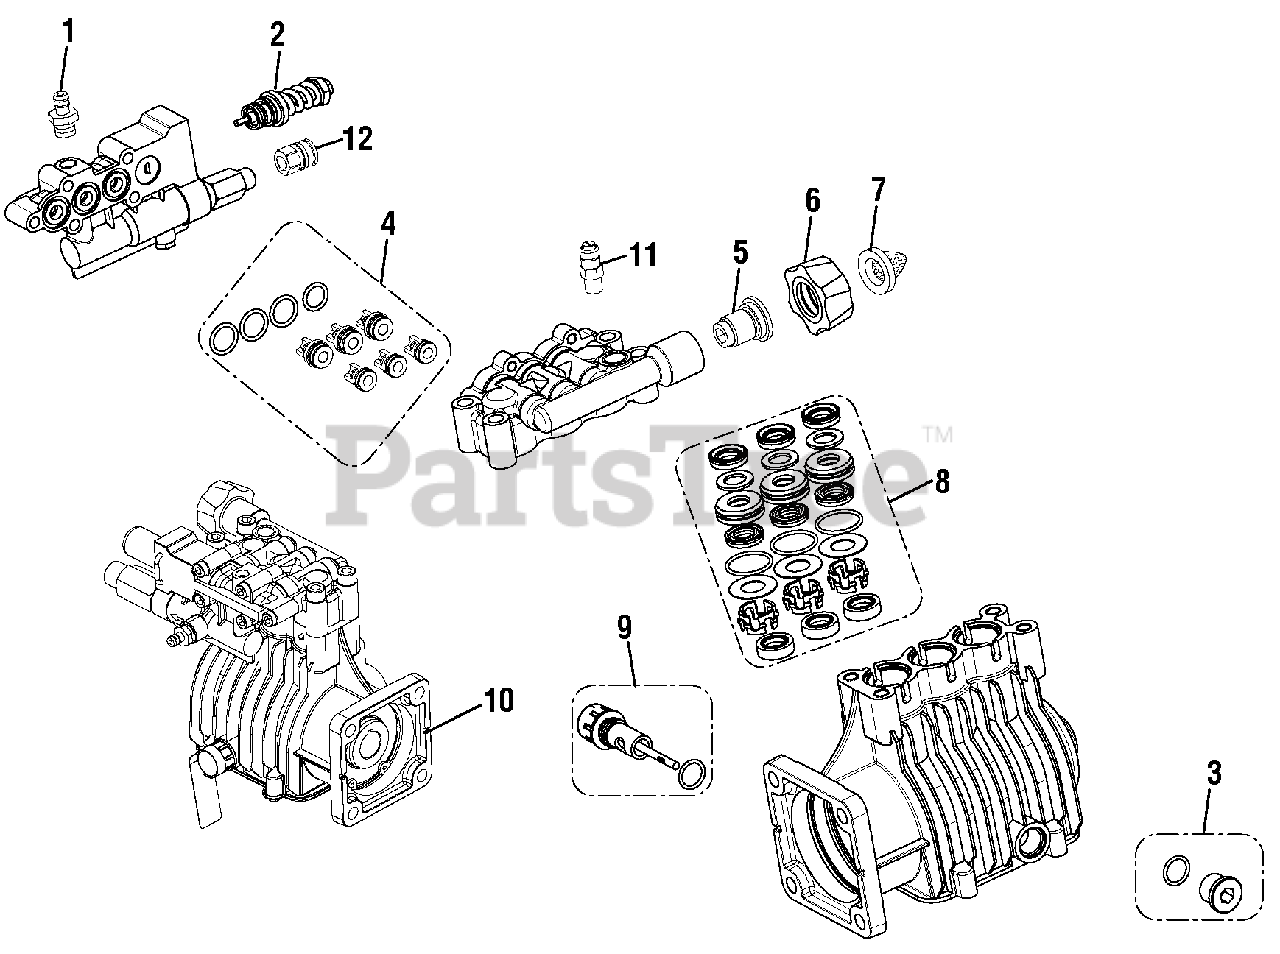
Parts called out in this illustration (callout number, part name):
1	Detergent Suction Kit
2	Unloader Assembly
3	Drain Plug Replacement Kit
4	Valve Replacement Kit
7	Filter Screen
8	Seal Replacement Kit
9	Breather Plug Replacement Kit
10	Pump
11	Thermal Release Valve
12	Quick Connect (3/8 in. NPT)
